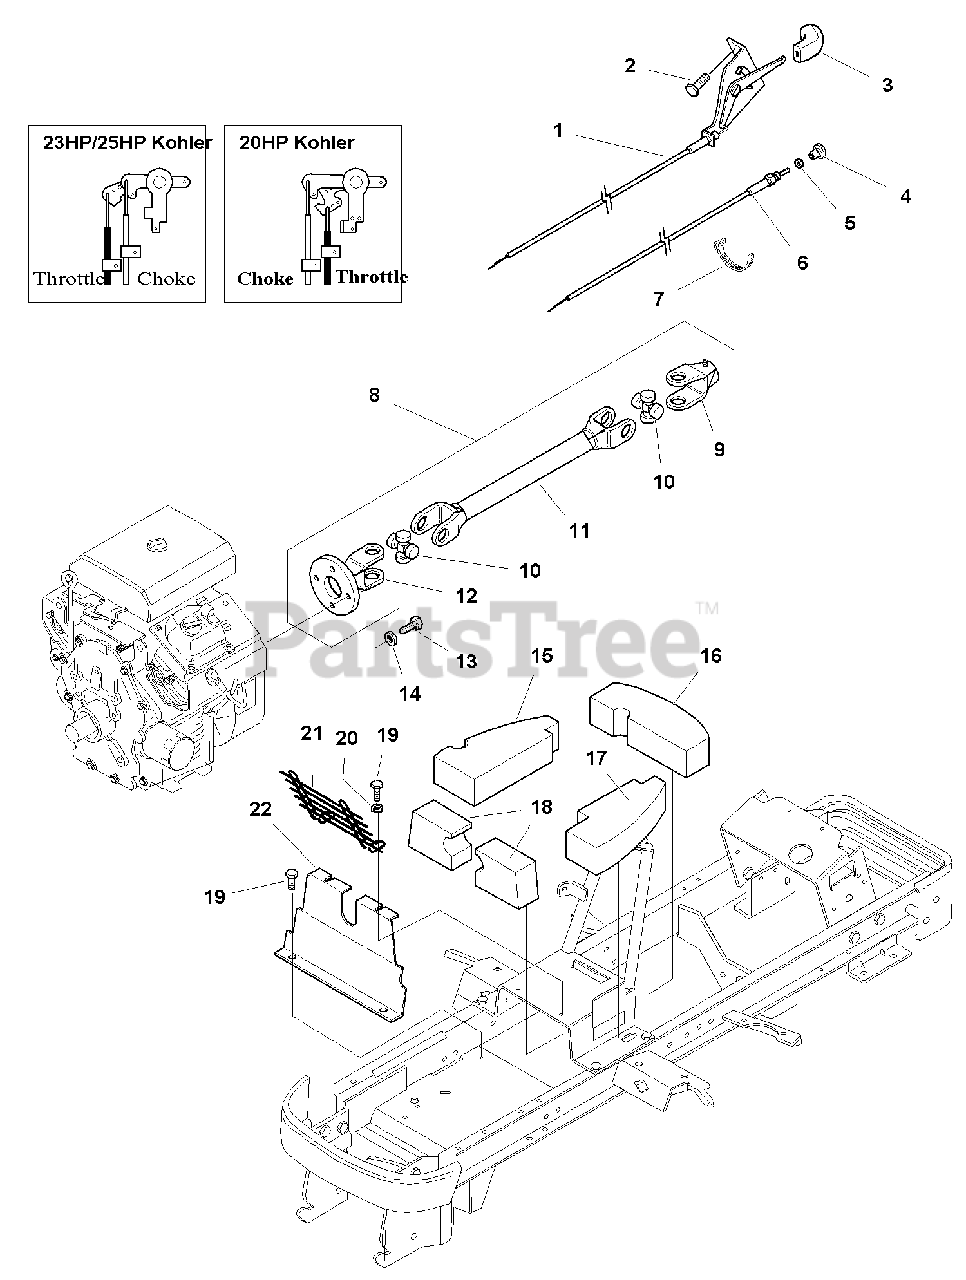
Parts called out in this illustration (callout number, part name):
1	CONTROL, Throttle
2	CAPSCREW, Plastite
3	KNOB, Throttle
4	KNOB, Choke
5	NUT, Hex, #10-24
6	CONTROL, Choke
8	DRIVESHAFT ASSEMBLY (Includes Ref. Nos. 9-12)
10	CROSS & BEARING KIT
11	YOKE & TUBE ASSEMBLY
12	YOKE & FLANGE ASSEMBLY
13	SCREW, Socket Head. M8 x 1.75 x 20mm
14	LOCKWASHER, Internal Tooth
15	SEAL, RH Tunnel
16	SEAL, Rear Tunnel
17	SEAL, LH Tunnel
18	SEAL, Driveshaft
19	CAPSCREW, Hex Head, Taptite, 5/16-18 x 3/4
20	WASHER, .34 ID x .69 OD x .06
21	SHIELD, Drive Shaft
22	SHIELD, Air, Driveline
